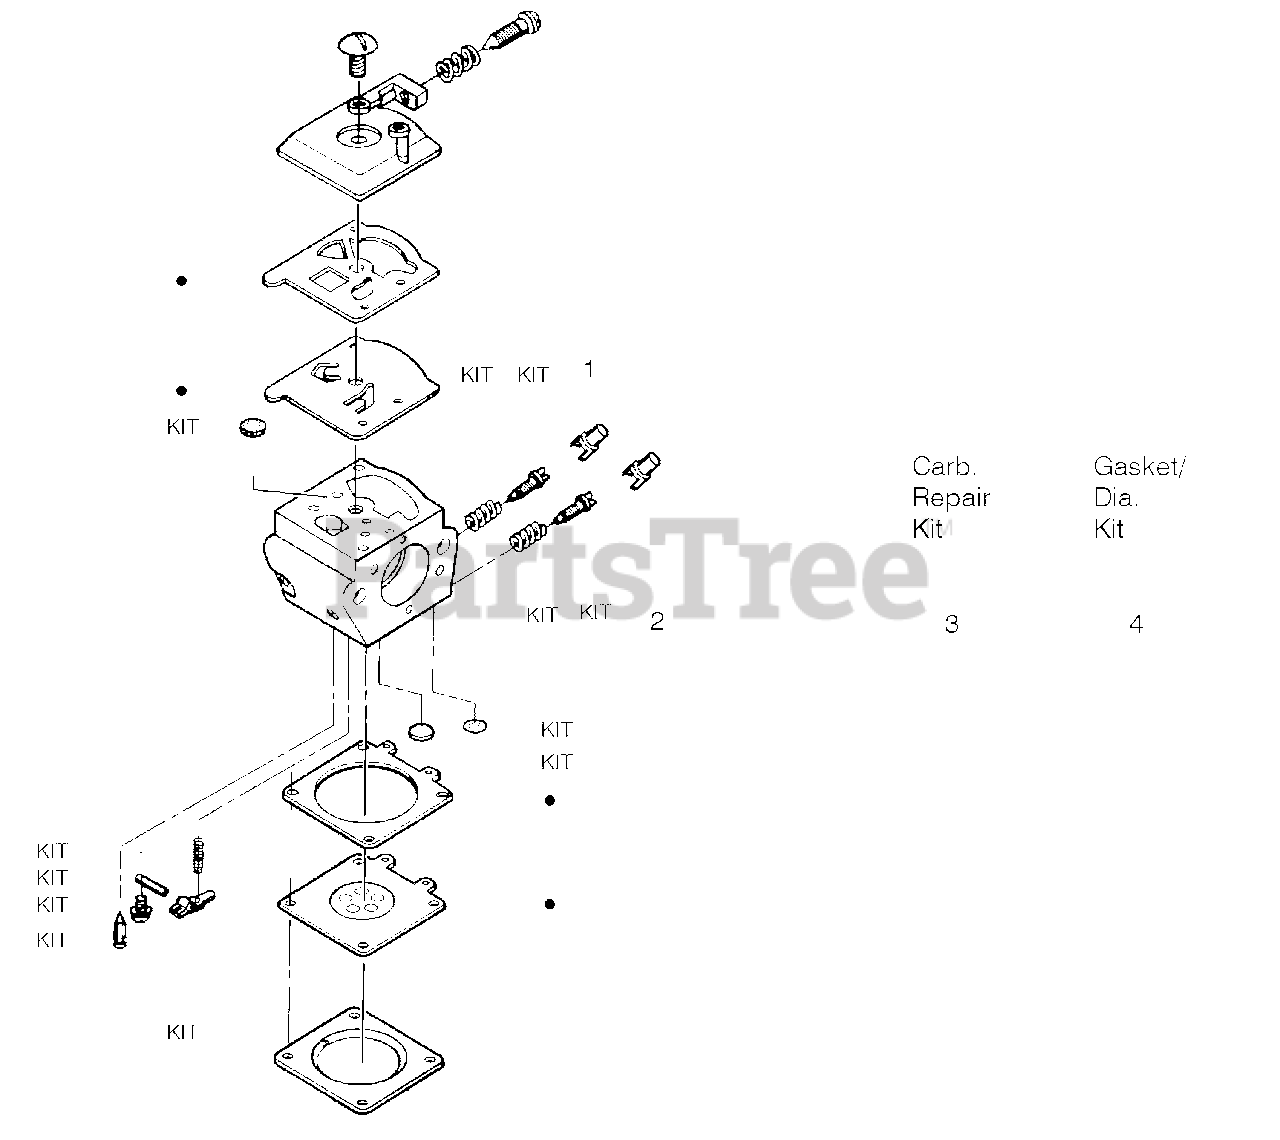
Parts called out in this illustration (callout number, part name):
1	Limiter Cap-High
2	Limiter Cap-Low
3	Carburetor Repair Kit
4	Gasket Diaphragm Kit
